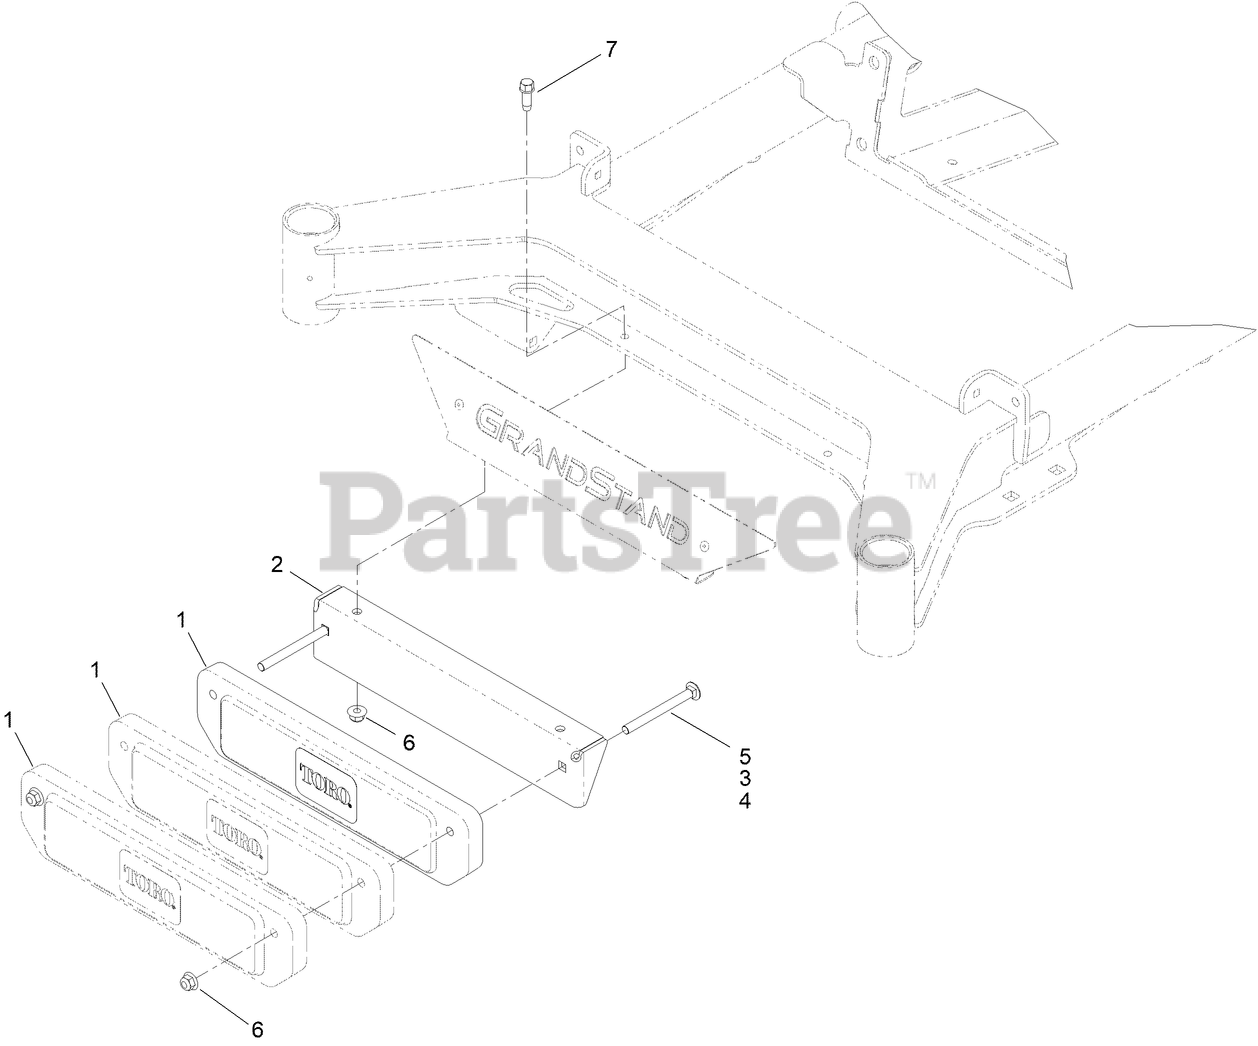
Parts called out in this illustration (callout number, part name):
1	WEIGHT-CAST
2	PLATE-MOUNT, WEIGHTS
3	SCREW-CARR
4	SCREW-CARR
5	SCREW-CARR
6	NUT-HF, NI
